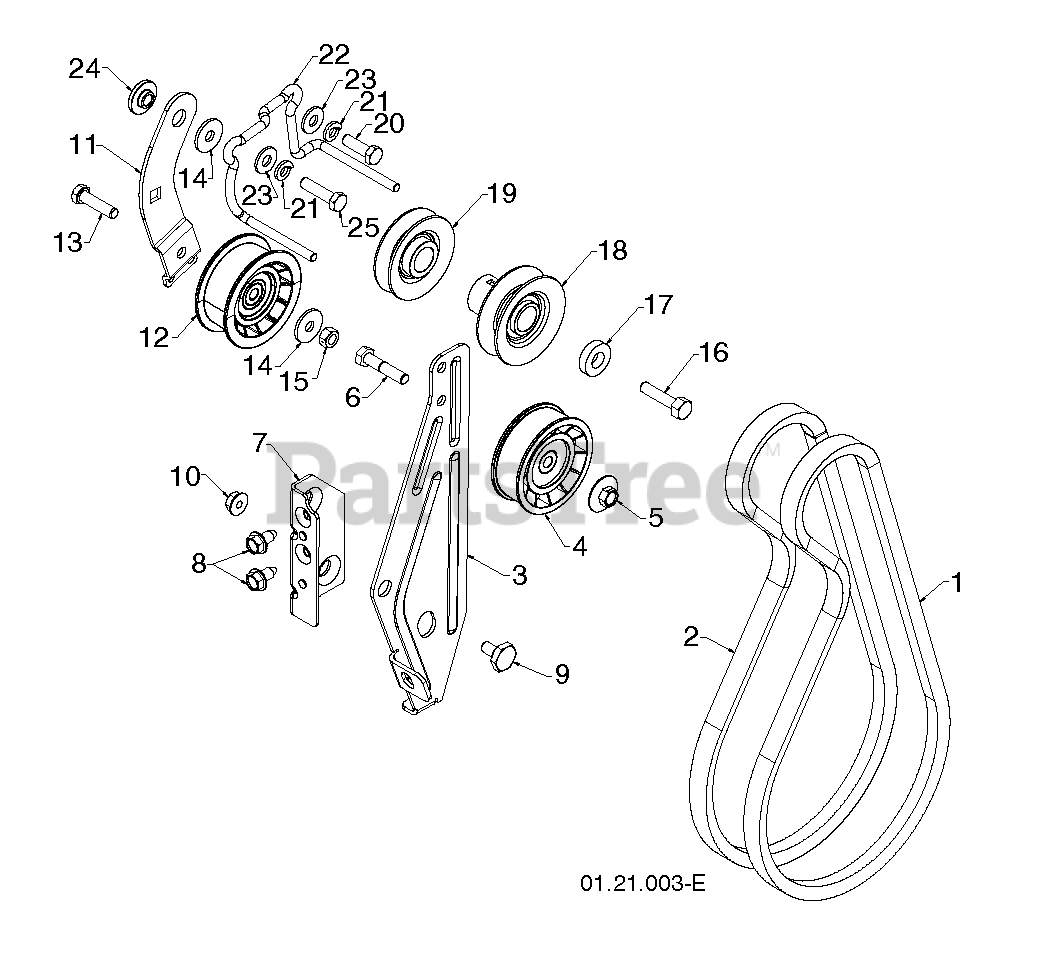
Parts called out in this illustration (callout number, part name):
1	BELT.V.IMPELLER
2	V-BELT TRACTION 34.25
3	ARM.IDLER BRAKE.CLEAR.ZINC
4	PULLEY.W/SPACER.2.75
5	NUT.FLANGE.HEX.5/16X18.BLACK
6	HEX BOLT
7	BRACKET.IDLER.PIVOT.ZINC
8	BOLT.5/16HEX.WHS.HD
9	BOLT.SHOULDER.1/2X12
10	NUT.LOCK.5/16-18
11	ARM, IDLER
12	PULLEY.IDLER.3.0X1.0.W/SPACER
13	BOLT.5/16-18X1-1/4 FULL.THREAD
14	STEEL WASHER
15	NUT.71038.31-18.HEX.NYLOCK
16	SCREW, HEX HD 3/8-24 X 1-3/8
17	WASHER, FLAT 3/8
18	PULLEY.IMPELER.
19	PULLEY.ENG.TRACTION
21	LOCKWASHER
22	RB GUIDE.BELT.CHAIN.LS.SNOW
23	WASHER.20X8.5
24	RP BUSHING, IDLER PIVOT
25	CAPSCREW.HEXHD.5/16X1.25.
